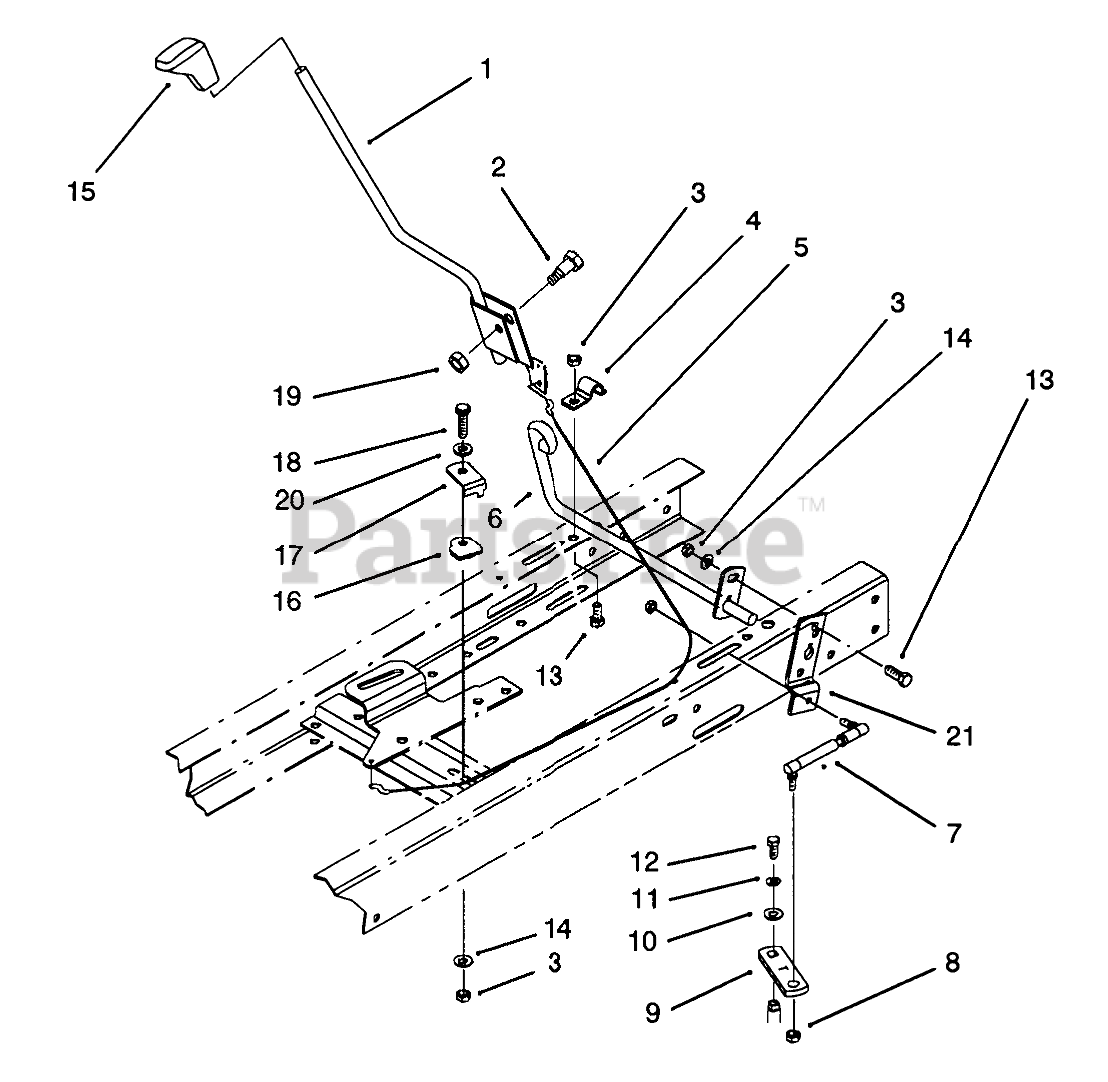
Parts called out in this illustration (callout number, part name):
1	Lever-Shift
2	SHOULDER BOLT
3	NUT-LOCK, NI
4	CLAMP-PIVOT, SHIFT
5	CABLE-CLUTCH
6	SHIFT PIVOT WAB
7	TIE ROD, SHIFT
8	NUT-LOCK
9	LEVER-SHIFT
10	SPACER
11	WASHER-LOCK
12	SCREW-HH
13	SCREW-HH
14	WASHER-PLAIN
15	SHIFT KNOB
16	GUIDE-CABLE
17	KEEPER-CABLE
18	SCREW-CARR
19	NUT-LOCK, NI
20	WASHER-FLAT
21	SHIFT LEVER PIVOTB
